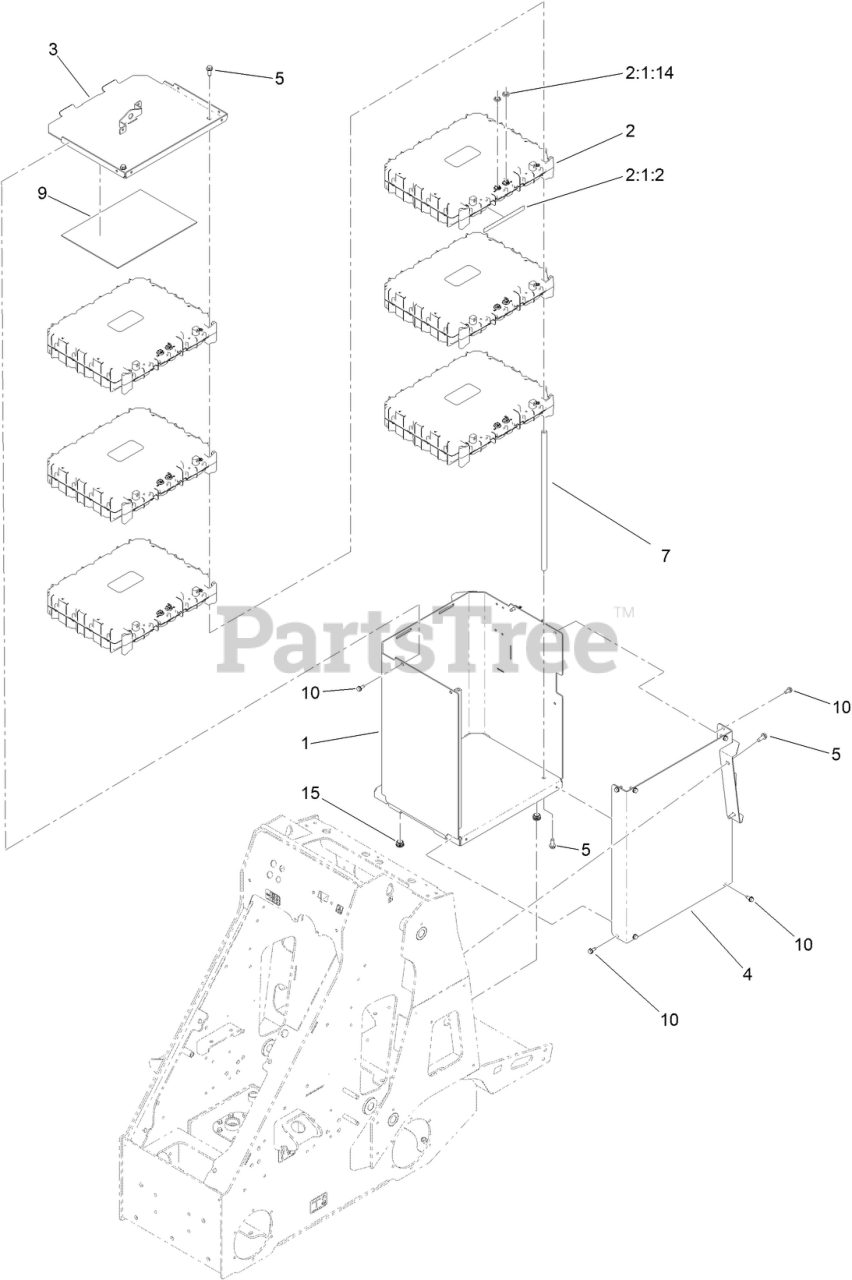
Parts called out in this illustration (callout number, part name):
1	BASE-BATTERY, BOX [PRIMED]
2	BATTERY ASM
2:1:2	DECAL-WARNING, BATTERY
2:1:14	NUT-MOUNTING, JWPF PANEL LOCK
3	COVER-BATTERY [PRIMED]
4	MOUNT-BATTERY [PRIMED]
5	SCREW-HWH
7	LOCK-BATTERY
9	FOAM-BATTERY BOX
10	SCREW-THD ROLL, HWH
15	GLIDE-BATTERY BOX
